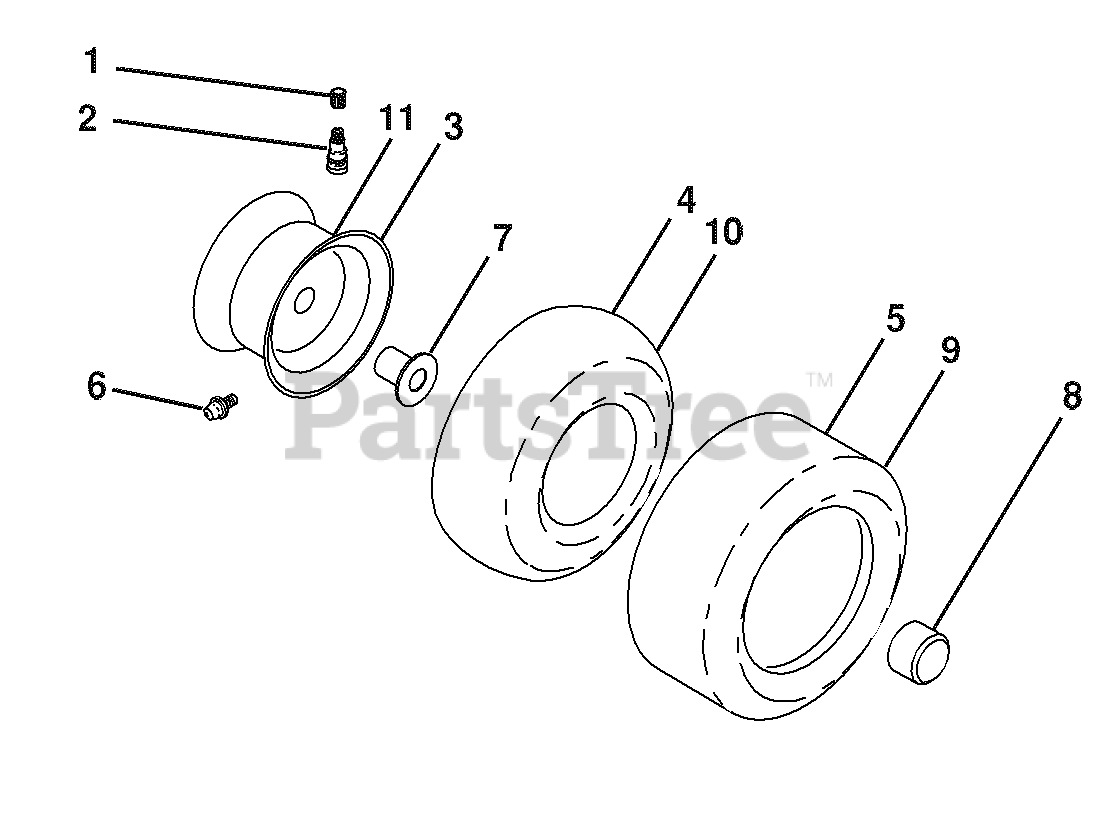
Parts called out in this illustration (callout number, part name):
1	Cap Valve Tire
2	Stem Valve
3	Tire F T 15 x 6 0 - 6 Service
4	Tube Front
5	Rim Asm 6" front Service
6	Fitting Grease
7	Bearing Flange
8	Cap Axle Blk 1 50 x 1 00
9	Tire R T 18 x 9.5-8 Service
10	Tube Rear
11	Rim Asm 8" rear Service
